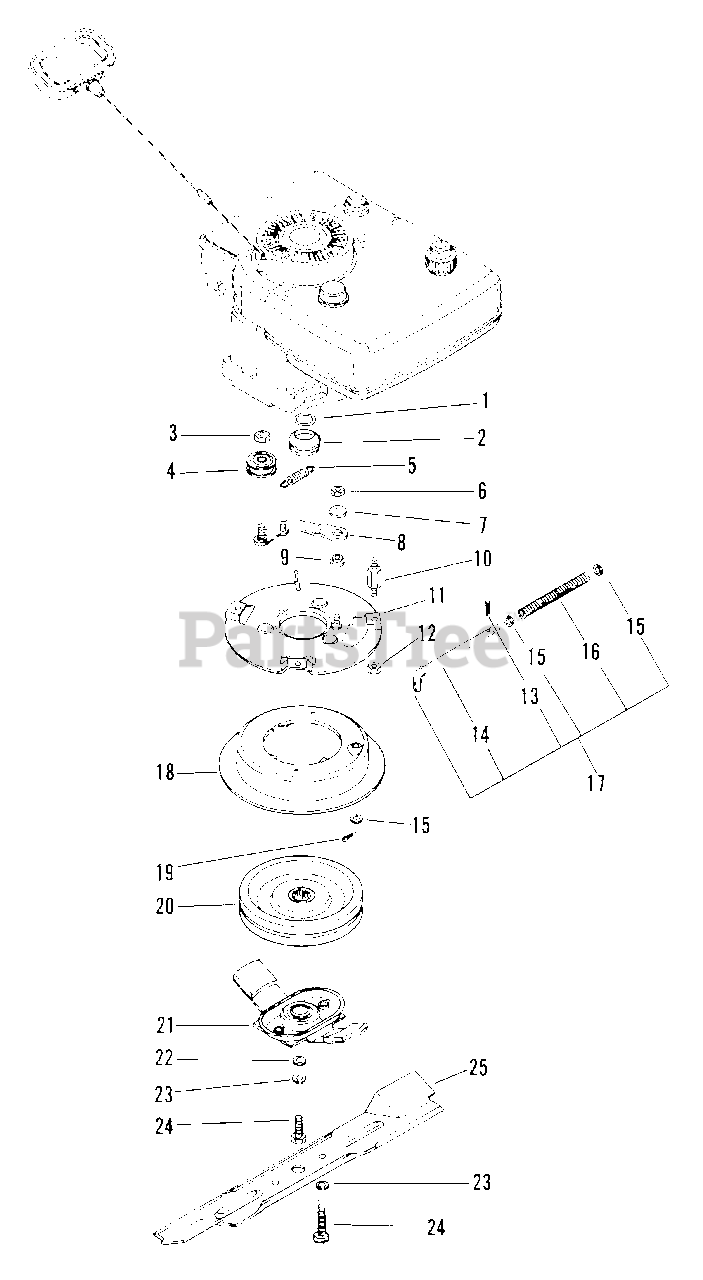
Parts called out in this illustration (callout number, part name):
1	RG-RTNG-EXT.875X.075
2	SHEAVE-BBC
3	NUT-LK-CTR .375-16 GR A PL
4	IDLER-FLAT 1.50 X .39 CLARK
5	SG-TENS .48X.44X2.0 5.0 WLD
6	NUT-LK-CTR .250-20 PL
7	WSHR-FL-STL .328X1.0X.094 PL
8	IDLER ARM WELDMENT BBC
9	BSHG-FLG .325X.498X.265X.88
10	HEX STUD
11	ASM - RAMP
12	NUT-FLG. .312-18 PL
13	PIN-HAIR INT .06X.18X.77
14	ROD,RETURN BBC
15	WSHR-FL-STL .328X.555X.06 PL
16	SG-COMP .080X.550X8.50 WLD38
17	ROD RETURN ASSEM.
18	ACTUATOR,BRAKE
19	@PIN-CTR .07X.50 EXTPRSQCT YZC
20	BBC FLYWHEEL
21	BBC LEAF SPRING AND BEARING AS
22	WSHR-FL-STL .382X1.25X.130
23	WSHR-LK .375X.115 HVY PL
24	BLT-HEX .38-24X1.25 PL GR5
25	BLADE, 21" MOWER
